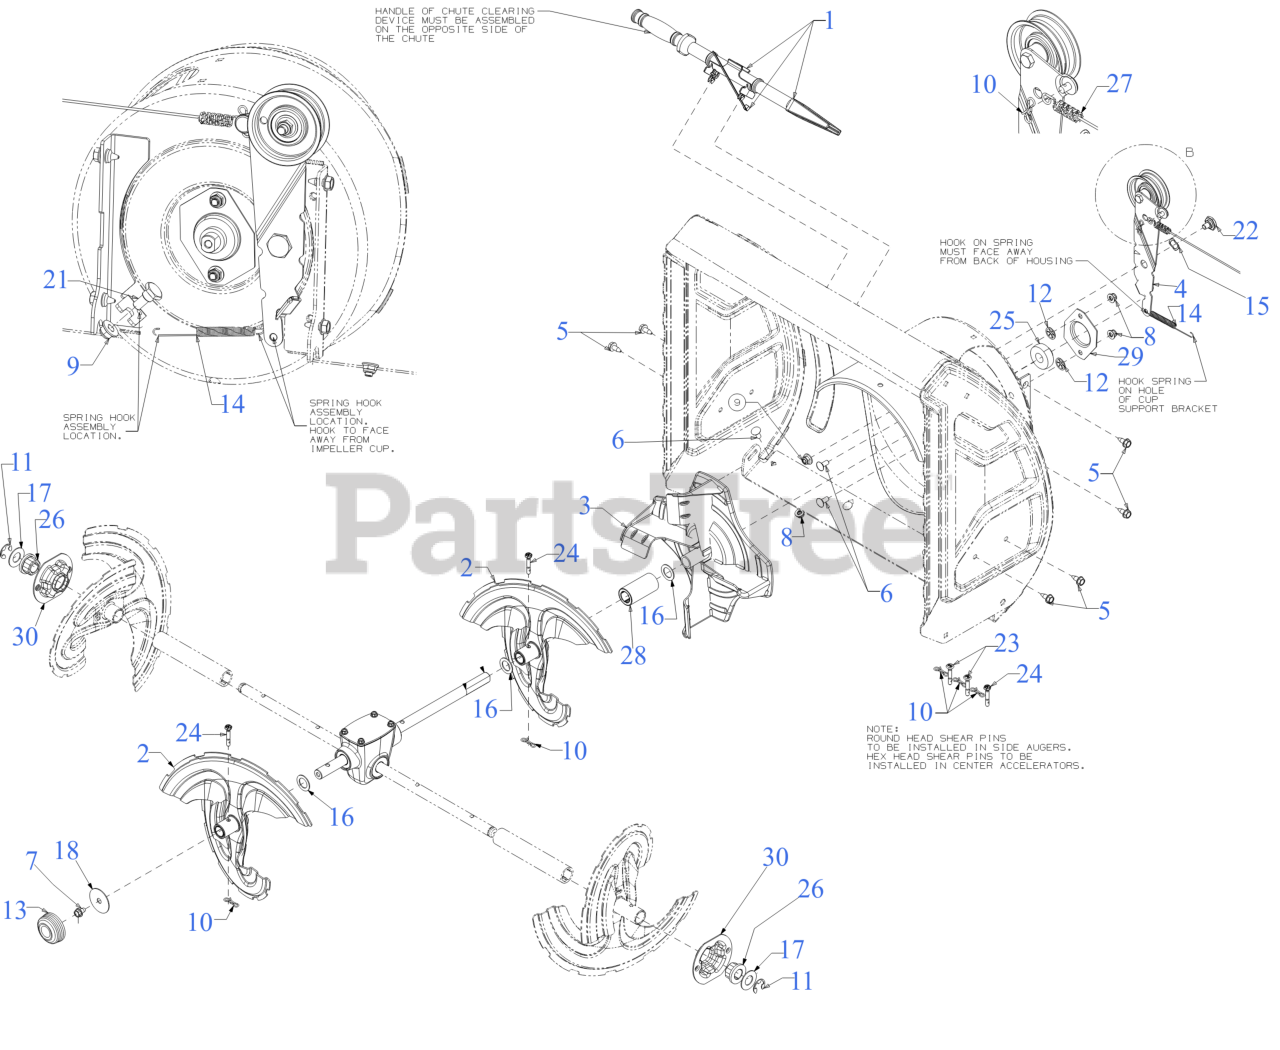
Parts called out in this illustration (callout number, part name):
1	CLEANOUT TOOL
1	CLEANOUT TOOL MOUNTING CLIP
2	ACCELERATOR AUGER W/BUSHNG (POWDER BLACK)
4	IDLER BRACKET
4	FLAT IDLER PULLEY 2.75 OD
4	HEX SCREW 3/8-16 x 1.75 GR5
5	SCREW 5/16-18 x .750
6	CARRIAGE BOLT 5/16-18 x .75
7	SCREW 5/16-18 x .500
8	FLANGE LOCK NUT 5/16-18
10	BOW TIE COTTER PIN 1/4-5/16
12	PUSH ON NUT
14	EXTENSION SPRING .38 OD x 4.59
15	WAVE WASHER .660 ID X.88 OD x .010
16	FLAT WASHER .793ID x 1.24OD x .060
17	FLAT WASHER
18	HUB CAP WASHER .406 x 1.92 x .060
21	SHOULDER SCREW .498 DIA x .340
22	SHOULDER SCREW .625
23	SHEAR PIN (.25 x 1.50)
24	SHEAR PIN (.25 x 1.5)
24	Cub Cadet SHEAR PINS (3X SNOW)
24	Troy-Bilt SHEAR PINS (3X SNOW)
24	KIT-SHEAR PIN 3 STAGE (05273/06654)
25	BEARING W/OUT COLLAR
26	FLANGE BEARING
27	AUGER CABLE 47.48 LG
29	BEARING HOUSING 1.85 ID
